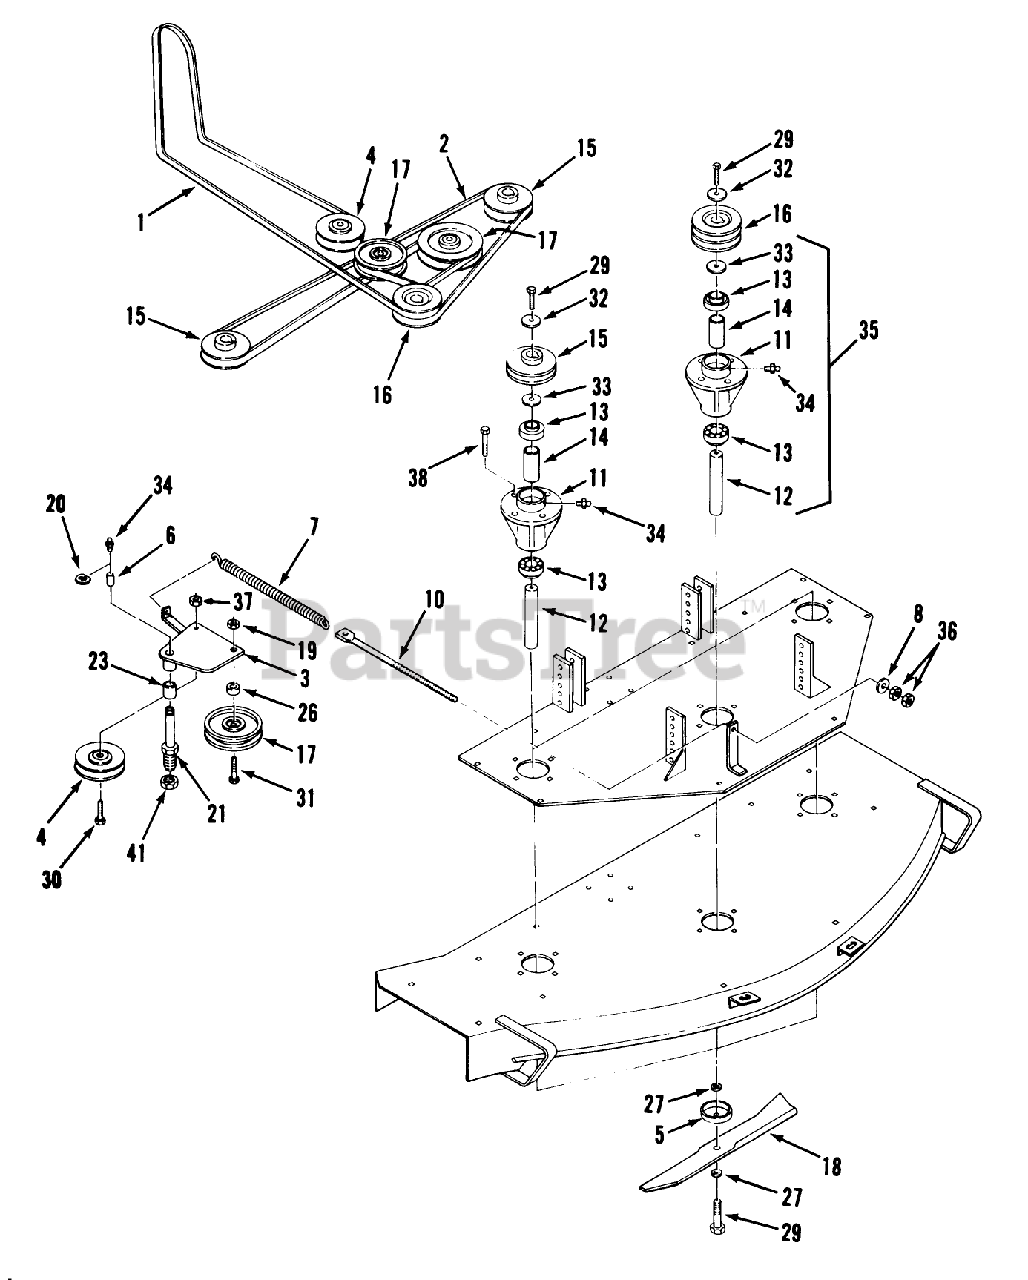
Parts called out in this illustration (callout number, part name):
1	BELT-50" MOW DR 724Z
2	BELT-V
3	Belt Tensioning Swing Arm
4	PULLEY-IDLER
5	CUP-SPINDLE
6	BUSHING
7	Spring-Idler
8	Collar
10	Spade Eyebolt
11	HOUSING-SPINDLE
12	SHAFT-SPINDLE
13	BEARING-BALL
15	PULLEY-OUTER
16	PULLEY-CENTER
17	PULLEY FLAT B
18	MOWER BLADE 17"
19	Nut
20	RETAINING RING
21	SHAFT-BELT TEN PI
23	SLEEVE R
26	SPACER
27	WASHER-SPECIAL
29	Bolt
30	Bolt
31	Bolt 1/2-13 X 2
32	WASHER-SPECIAL
33	SPACER
34	Zerk
35	Spindle Complete (includes items 11, 12, 13, 14, 29, 32, 33 & 34)
36	Nut
37	NUT
38	BOLT
41	Elast Nut 3/4-16
